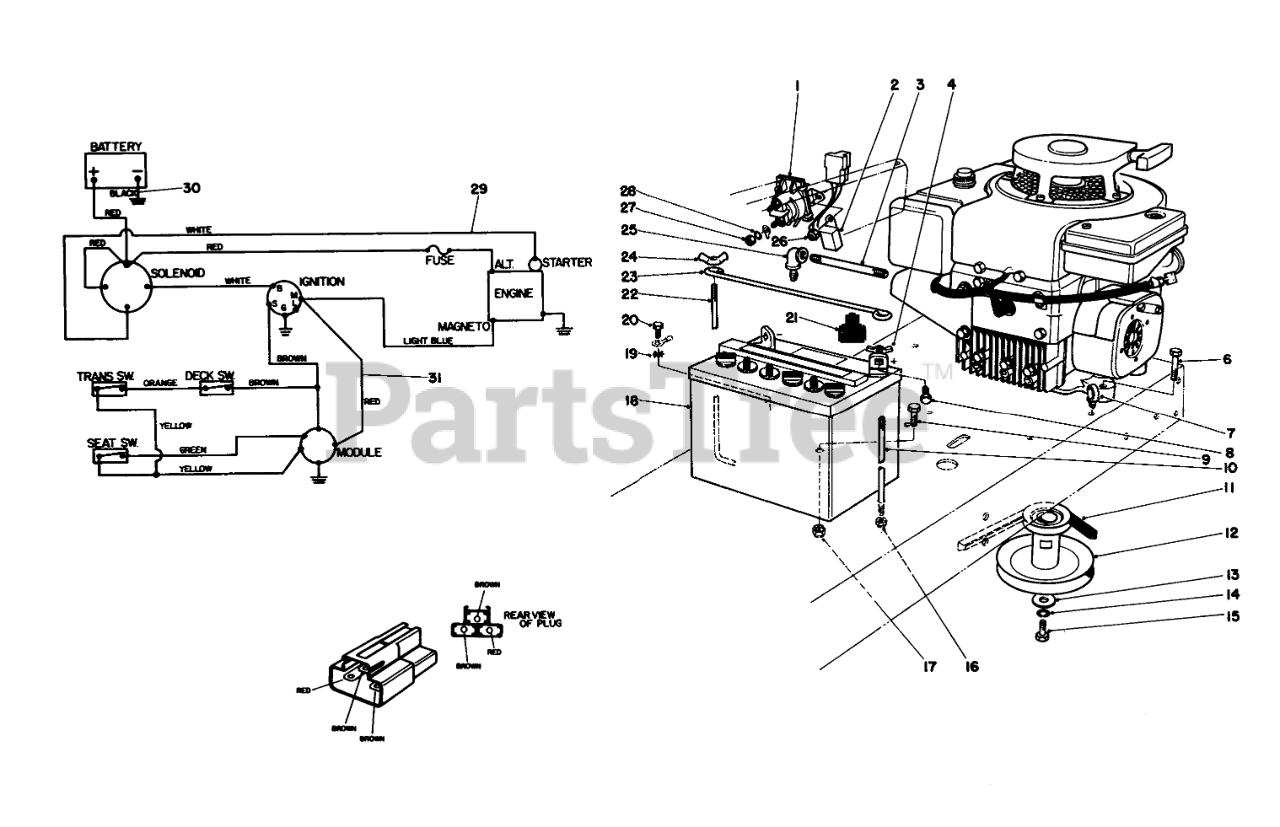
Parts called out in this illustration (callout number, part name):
1	Solenoid
2	INTERLOCK MODULE
3	NIPPLE
4	NUT-WING
6	SCREW-HH
7	Clip-Cable
8	SCREW-HH
9	SCREW-HH
10	BATTERY BOLT
11	V-BELT, TRACTION
12	PULLEY
13	WASHER
14	WASHER-LOCK
15	SCREW-HH
16	NUT-KEPS
17	NUT-LOCK, CONE
18	Battery
19	WASHER-LOCK, INTERNAL
20	SCREW-HHF
21	BOOT-TERMINAL
22	ROD-SUPPORT, BATTERY
23	BATTERY HOLD DOWN
24	NUT-WING
25	ELBOW-90 DEGEE
26	NUT-LOCK, CONE
27	NUT-JAM
28	WASHER-LOCK
29	Wiring Harness
30	Wire-Battery to Ground
31	Wiring Harness
